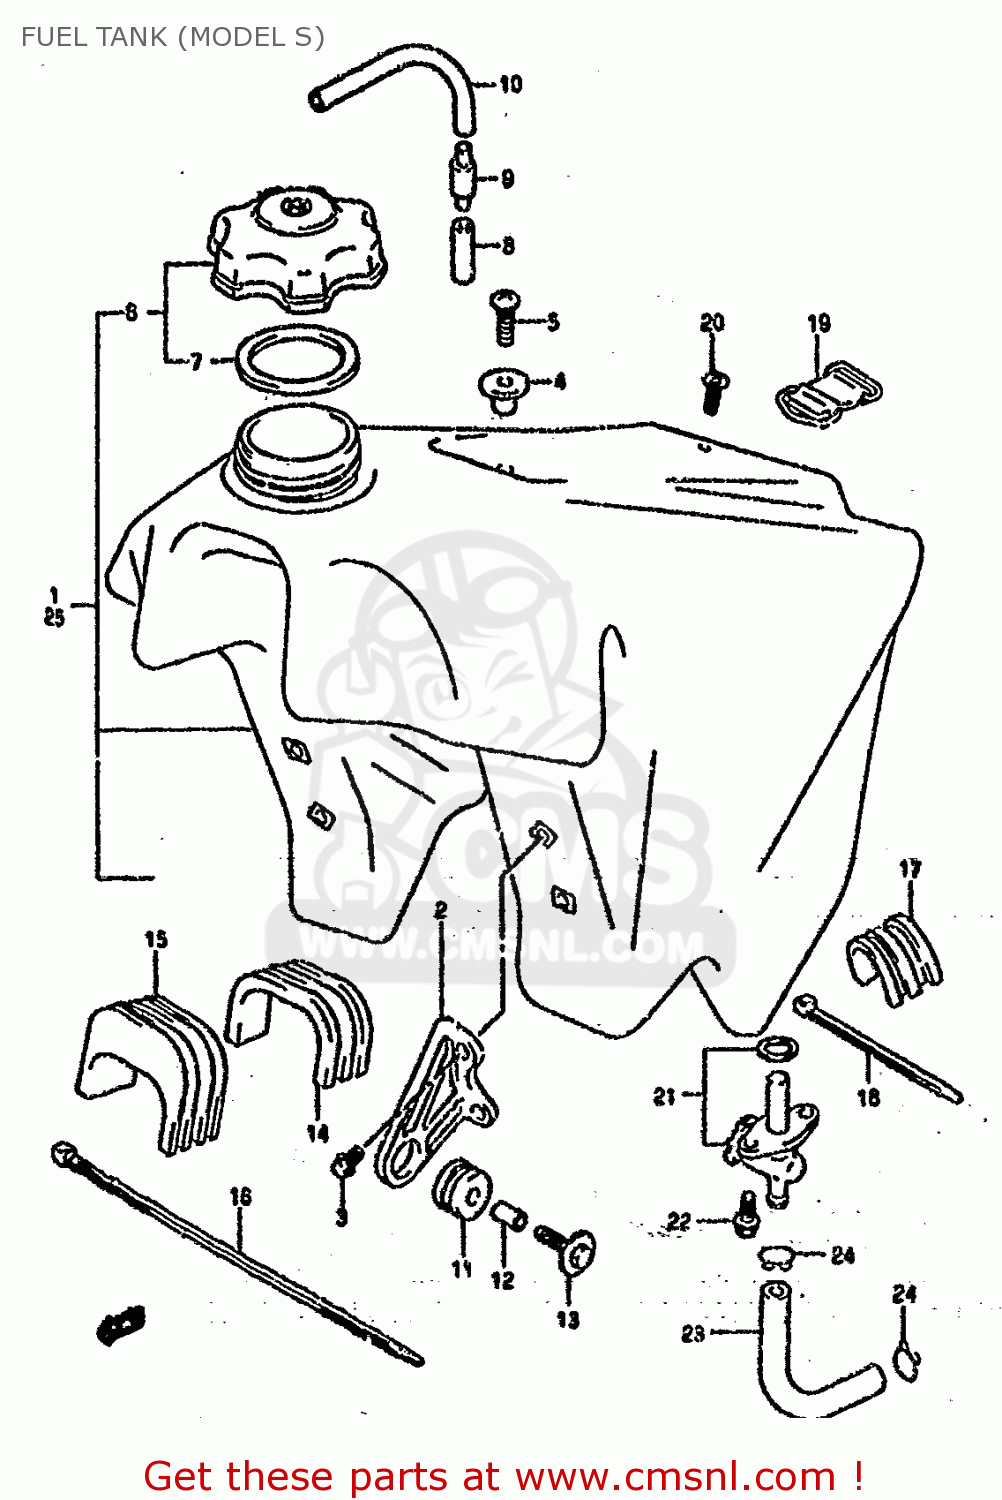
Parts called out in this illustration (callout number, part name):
1	TANK SET,FUEL
2	BRACKET,FUEL TANK,FRONT
3	BOLT
4	HOOK,SEAT FR
5	SCREW
6	CAP SET,FUEL TANK
7	GASKET,CAP (NAS)
8	HOSE(5X8.2X600)
9	PLUG,FUEL TANK BREATHER
10	HOSE(5X8.2X600)
11	CUSHION,MUFFLER
12	SPACER (6.4X9X13.5)
13	BOLT(6X30)
14	CUSHION,FUEL TANK NO.2
15	CUSHION,FUEL TANK
16	CLAMP(L:300)
17	CUSHION,FUEL TANK NO.2
18	CLAMP(L:145)
19	BAND,FUEL TANK RR
20	SCREW
21	COCK ASSY,FUEL
22	COCK ASSEMBLY,FUEL
23	SCREW
24	CLIP
25	CLIP
